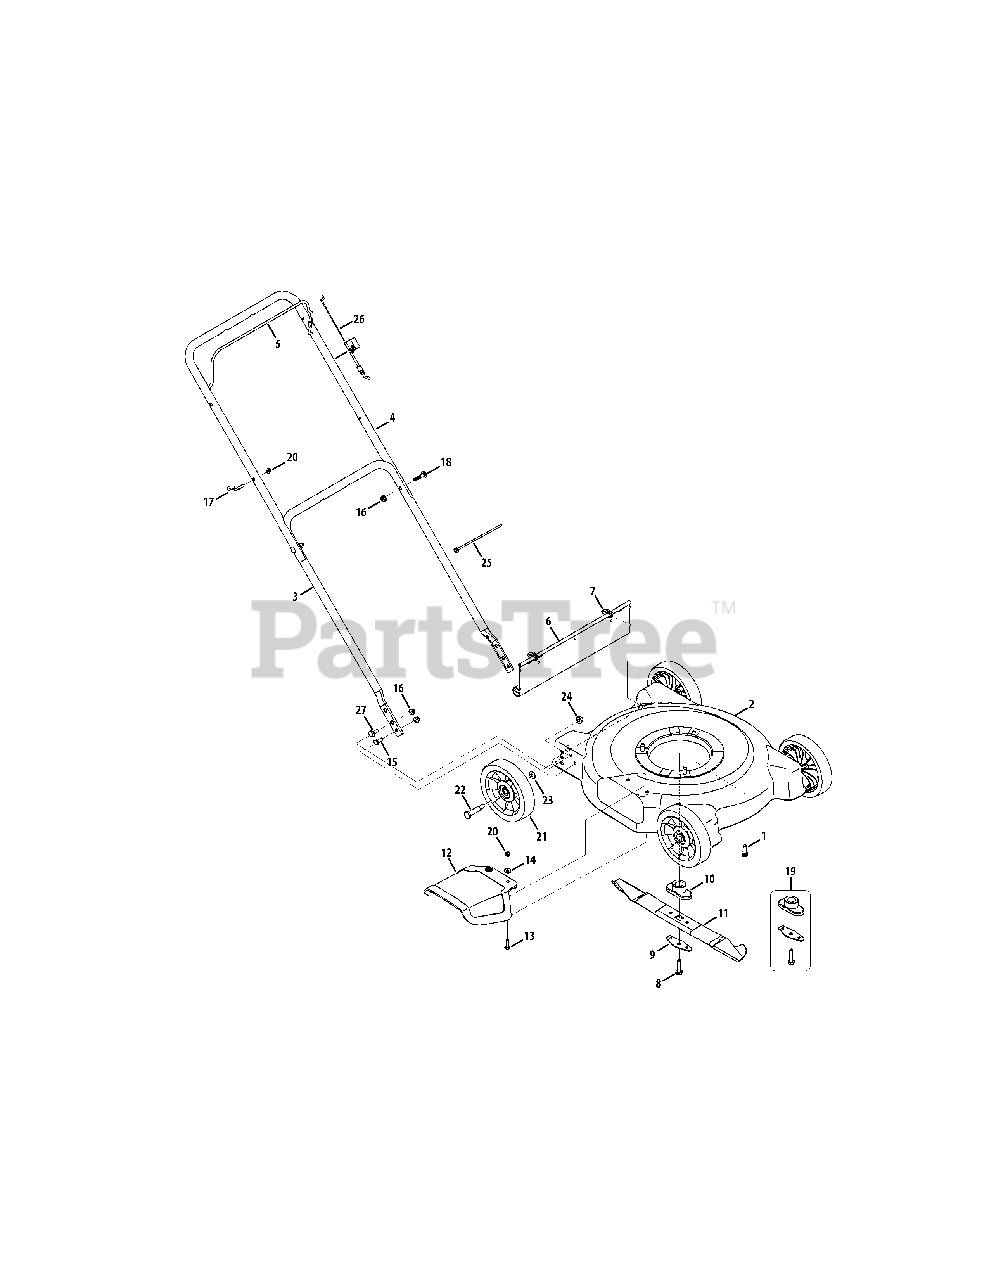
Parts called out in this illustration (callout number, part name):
1	Hex Ind. Washer Screw, 3/8-16 x 1.0
2	Cutting Deck, 20" - Red
4	Upper Handle
5	Blade Control
6	Rear Flap
7	Hinge Clip
8	Screw, 3/8-24 x 1.5"
9	Blade Bell Support
10	Blade Adapter
11	Cutting Blade
12	Discharge Chute
13	Carriage Screw, 1/4-20 x 1.0"
14	Flat Washer
15	Hex Screw, 5/16-18 x .75"
16	Flange Lock Nut, 5/16-18
17	Eye Bolt
18	Carriage Bolt, 5/16-18 x 1.5"
19	Blade Adapter Kit (Incl. Ref. 8-10)
20	Flange Lock Nut, 1/4-20
21	Wheel, 7" Star-Dia., Oys. Gray
22	Shoulder Screw, .498 x 1.635
23	Bell Washer
24	Flange Lock Nut, 3/8-16
25	Cable Tie
26	Control Cable, B&S Engine 37.25"
26	Control Cable, MTD OHV Engine 48"
27	Shoulder Screw, 5/16-18 x.428"
